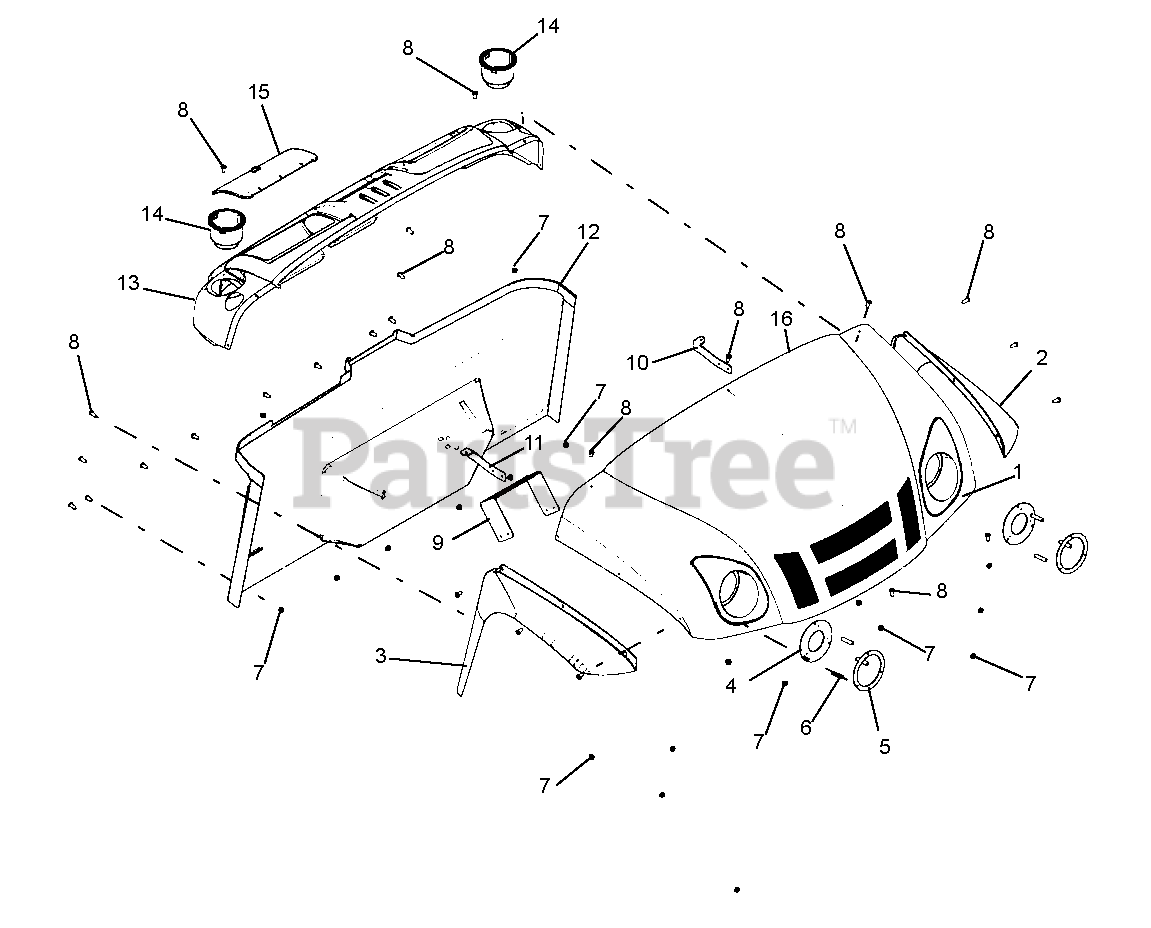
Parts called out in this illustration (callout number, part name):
1	KIT, HOOD WITH DECALS (996123, 125, 146)
2	FENDER, FRONT, LEFT HAND
3	FENDER, FRONT, RIGHT HAND
4	TOP FLANGE, HEADLIGHT
5	BASE FLANGE, HEADLIGHT
6	SPACER, HEADLIGHT
7	NUT, HEX FLANGE TL 1/4-20 ZNYCR
8	TTHMS 1/4-20 X 1 ZNYCR
9	BRACKET, MOUNTING SWITCH
10	BRACKET, CUPHOLDER, LEFT HAND
11	BRACKET, CUPHOLDER, RIGHT HAND
12	KIT, FOOTWELL WITH DECALS
13	DASH ASSEMBLY WITH DECALS
14	CUP, HOLDER SNAP-IN 3.75 OD
15	DOOR, GLOVEBOX ASSEMBLY
16	TRIM, 1/8 RUBBER EDGE
